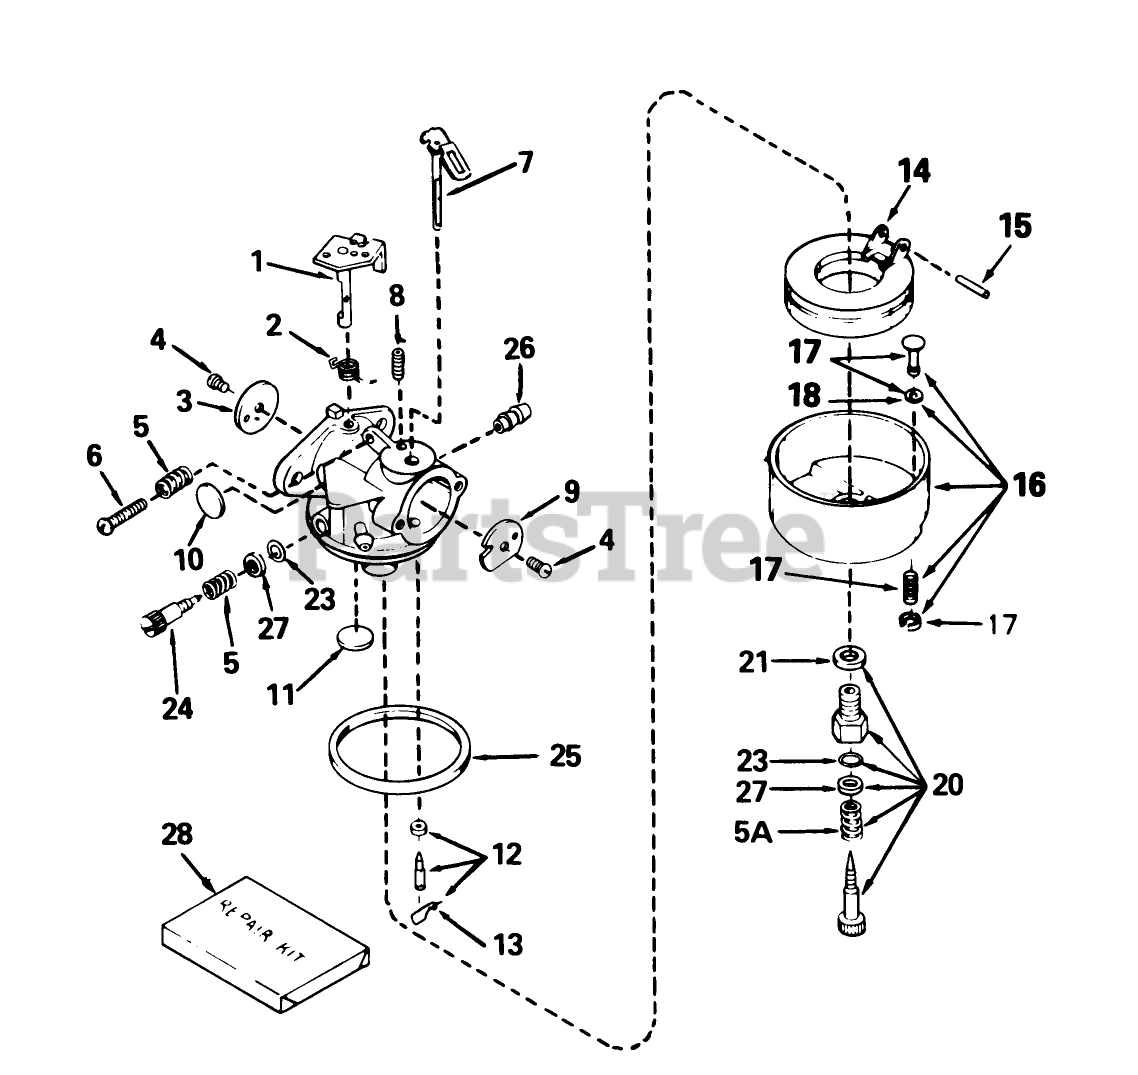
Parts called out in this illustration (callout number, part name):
1	Throttle Shaft and Lever ASM
2	Spring-Return, Throttle
3	Shutter-Throttle
4	Screw-Shutter
5	Spring-Tension
5A	Spring
6	Screw-Throttle Crack Screw / Idle Speed
7	Choke Shaft and Lever ASM
8	Spring-Positioning, Choke
9	Shutter-Choke
10	Plug-Welch, Idle Mixture Well
11	Plug-Welch, Atmospheric Vent
12	Inlet Needle, Seat Clip Assy. (Incl. No. 13)
13	Clip-Spring
14	Float
15	Shaft-Float
16	Float Bowl Asm. (Incl. Ref. # 32, 33)
17	Bowl Drain ASM
18	Gasket-Plunger, Drain
20	Adjustment Screw Assy.,Main (Incl. Ref. #5A,21,23 30)
21	Washer-Bowl Nut
23	ORing
24	Screw-Idle Mix
25	O Ring-Bowl, Float
26	Fitting-Fuel
27	Washer
28	Kit-Repair
